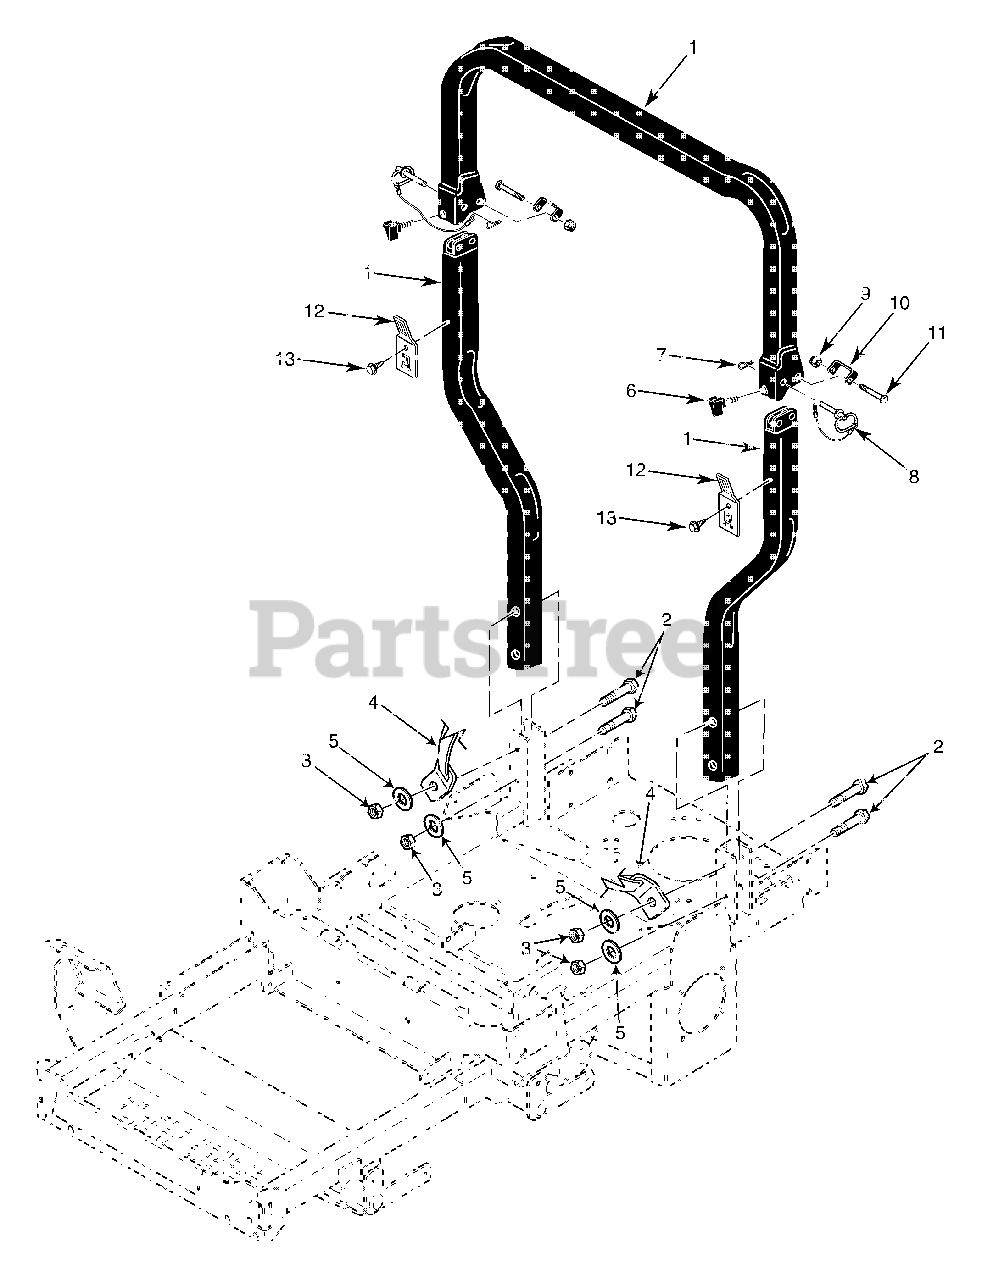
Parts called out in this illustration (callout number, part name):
1	STC Foldable ROPS Accessory
2	Bolt, Hex Head 1/2-13 x 3-1/2"
3	Nut, Center Lock 1/2-13
4	Seat Belt
5	Flatwasher, 1/2-.562 x 1.375 x .109
6	Thumb Screw, 5/16-18 NC x 3-4"
7	Hair Pin, Cotter
8	Pin
9	Nut, Center Lock 1/2-13
10	Bracket, Stop
11	Bolt, Hex Head 1/2-13 x 3-1/2"
12	Bracket, Seat Belt Hanger
13	Screw, 1/4-20 x 3/4"
